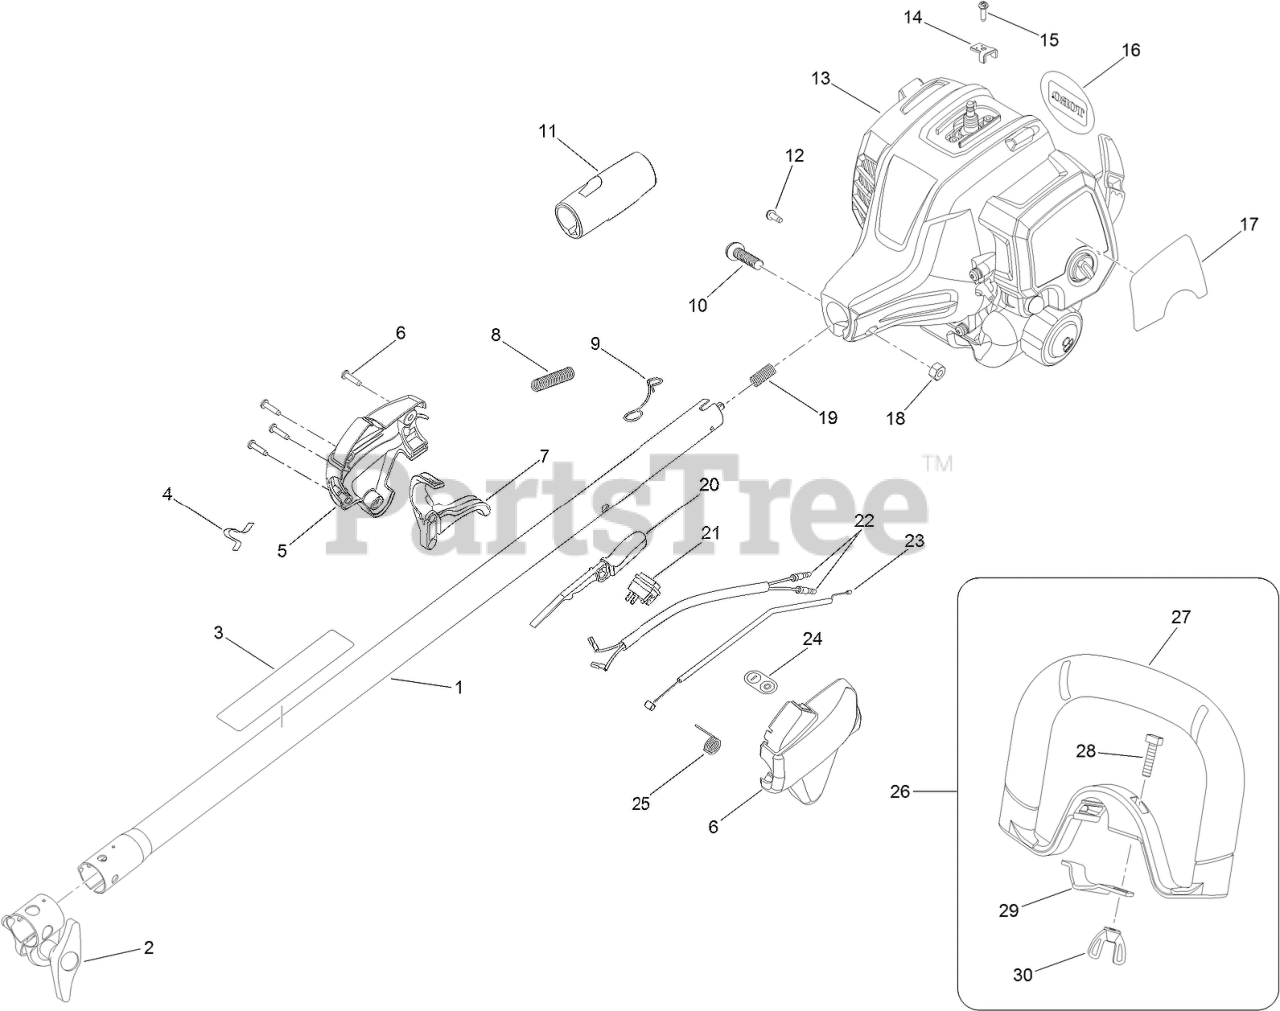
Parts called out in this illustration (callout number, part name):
1	UPPER SHAFT ASM
2	SHAFT CLAMP ASM
3	LABEL-WARNING
4	CLIP-STRAP, SHOULDER
5	CONTROL HANDLE ASM
7	TRIGGER-THROTTLE
8	TUBE-CORRUGATED
9	SPRING-CABLE, THROTTLE
11	GRIP-SHAFT, UPPER
13	Powerhead ASM
14	CLAMP-CABLE, THROTTLE
16	PLATE-LOGO
17	DECAL-START
18	NUT-HEX
19	SPRING-COMPRESSION
20	TRIGGER-LOCK, THROTTLE
21	SWITCH-ON/STOP
22	HARNESS-WIRE
23	CABLE-THROTTLE
24	LABEL-ON/STOP
25	SPRING-TRIGGER
26	HANDLE ASM
27	HANDLE-SHAFT, UPPER
29	CLAMP-HANDLE, UPPER SHAFT
30	NUT-WING
